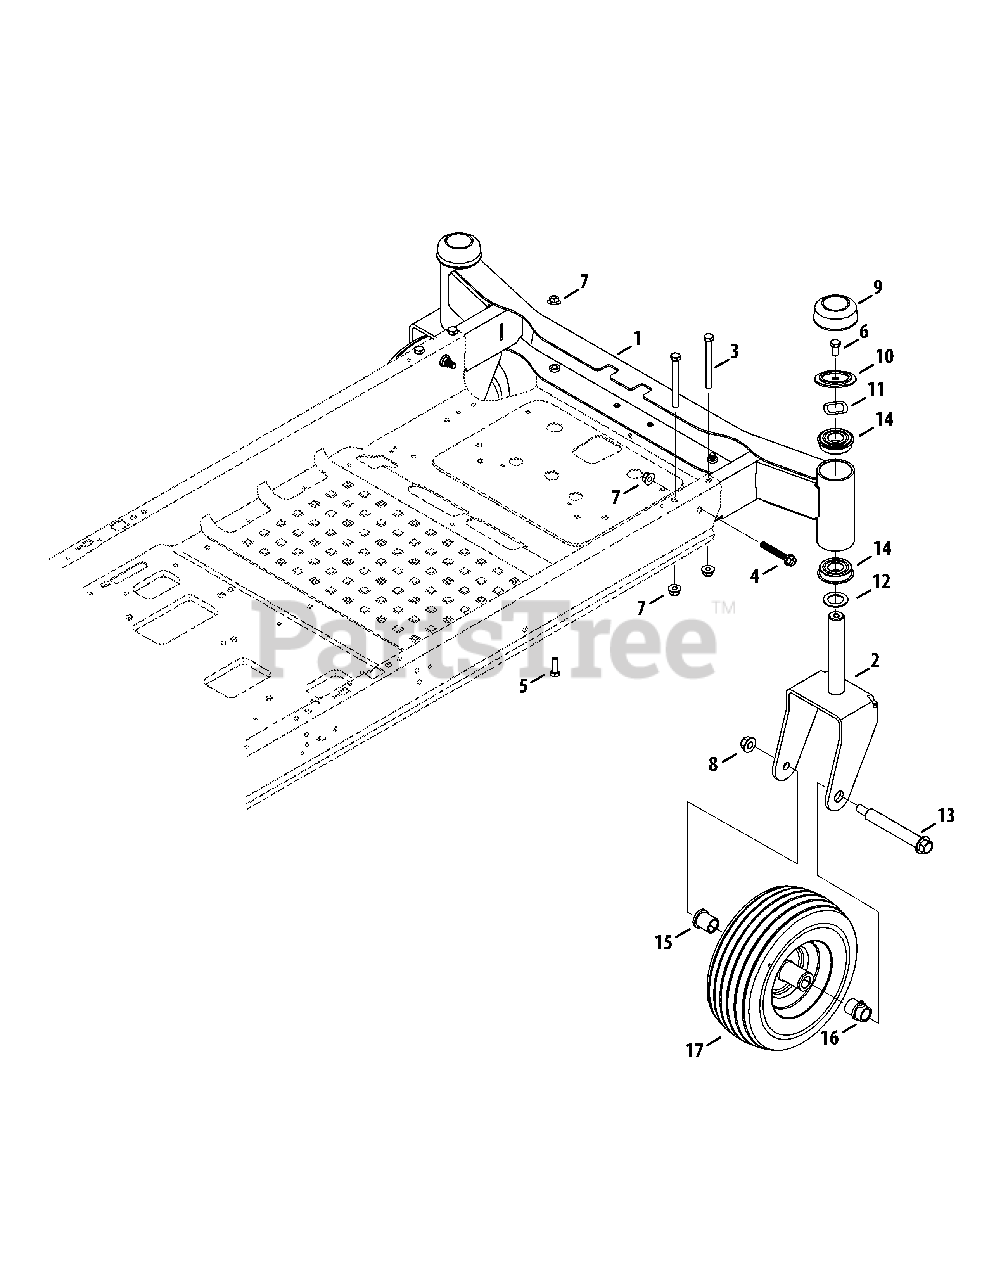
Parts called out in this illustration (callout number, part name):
2	Caster Wheel Bracket
3	Hex Cap Screw, 3/8-16 x 3.75
4	Hex Flange Screw, 3/8-16 x 2.00
5	Hex Cap Screw, 3/8-16 x 1.00
6	Hex Cap Screw, 3/8-16 x .750
7	Flange Lock Nut, 3/8-16
8	Flange Lock Nut, 1/2-13
10	Shoulder Spacer, 2.50 x .200
11	Wave Washer, 1.25 x 1.00 x .300
12	Flat Washer, 1.010 x 1.56 x .060
13	Shoulder Screw, 1/2-13
14	Ball Bearing
15	Flange Bearing, .76 x 1.0 x 1.2
16	Flange Bearing, .76 ID w/Lube Ftg.
17	Wheel Assembly, 11.0 x 4.0 x 5.0
